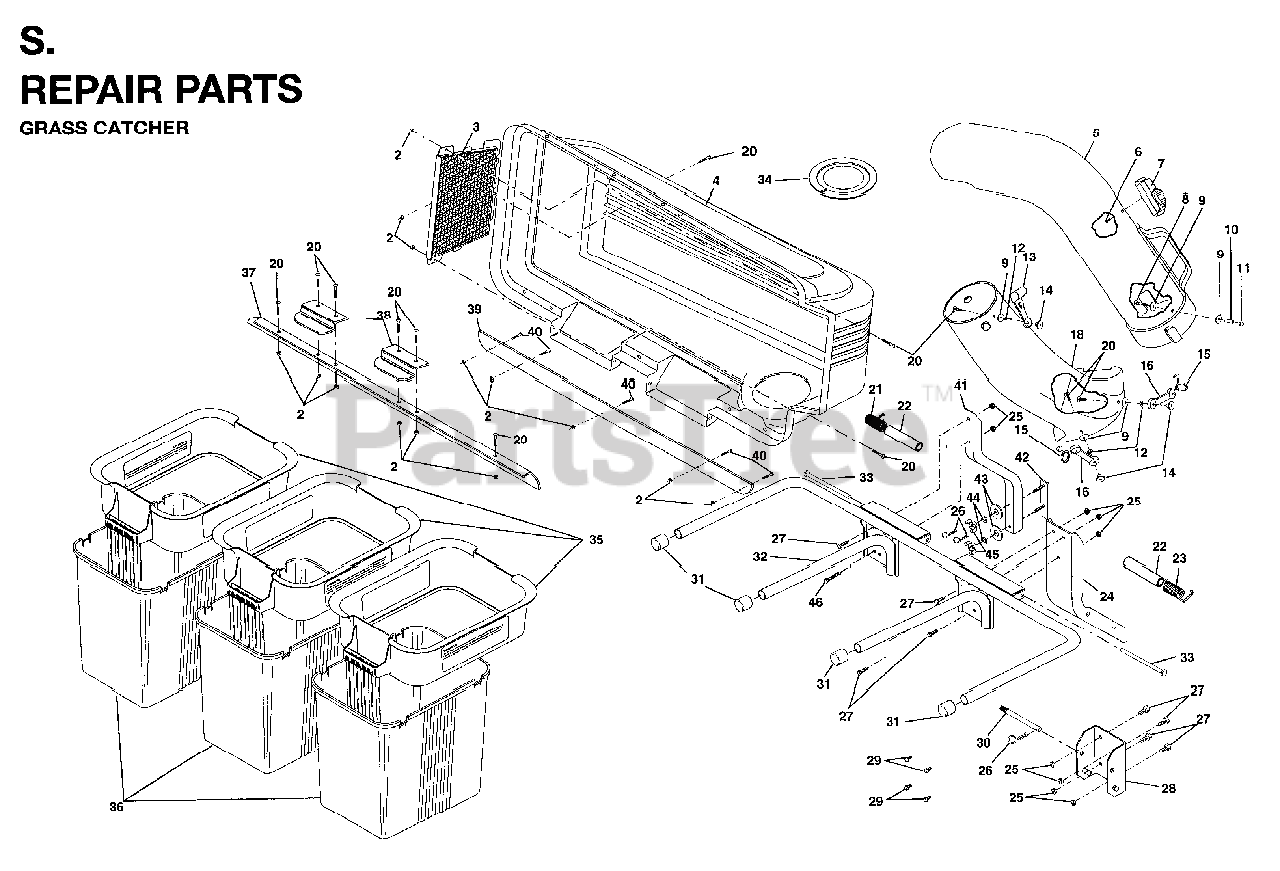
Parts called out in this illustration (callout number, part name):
3	COVER SCREEN
4	COVER BAGGER
5	CHUTE.UPPER.42"
7	INDICATOR DUMP BAG
8	RP SCREW
10	SPACER LT
11	NUT
12	LOCKWASHER
13	HOOD LATCH T
14	NUT.WELD.#10-24
15	HOOK LATCH
16	RUBBER LATCH
18	CHUTE.LOW.GT.46
20	SCREW.10-24X5/8
21	SPRING COVER LH
22	SPACER.COVER.BAGGER
23	SPRING COVER RH
24	POST, SUPPORT
25	LOCKNUT
26	RETAINER SPRING
27	BOLT
28	MTG BRACKET
30	SUPPORT POST PIN
31	TUBING PLUG
33	HINGE PIN
34	GASKET COVER
35	CONTAINER TOP
36	CONTAINER BOTTOM
37	BAGGER TOP SEAL
38	LATCH CER38
39	REINFORCEMENT STRIP
41	POST SUPT LIFT 3B
42	PLATE.ASM.REINFORCEMENT.BLACK
44	LOCKWASHER
45	NUT WING PM
46	BOLT FIN HEX 5/16-18
